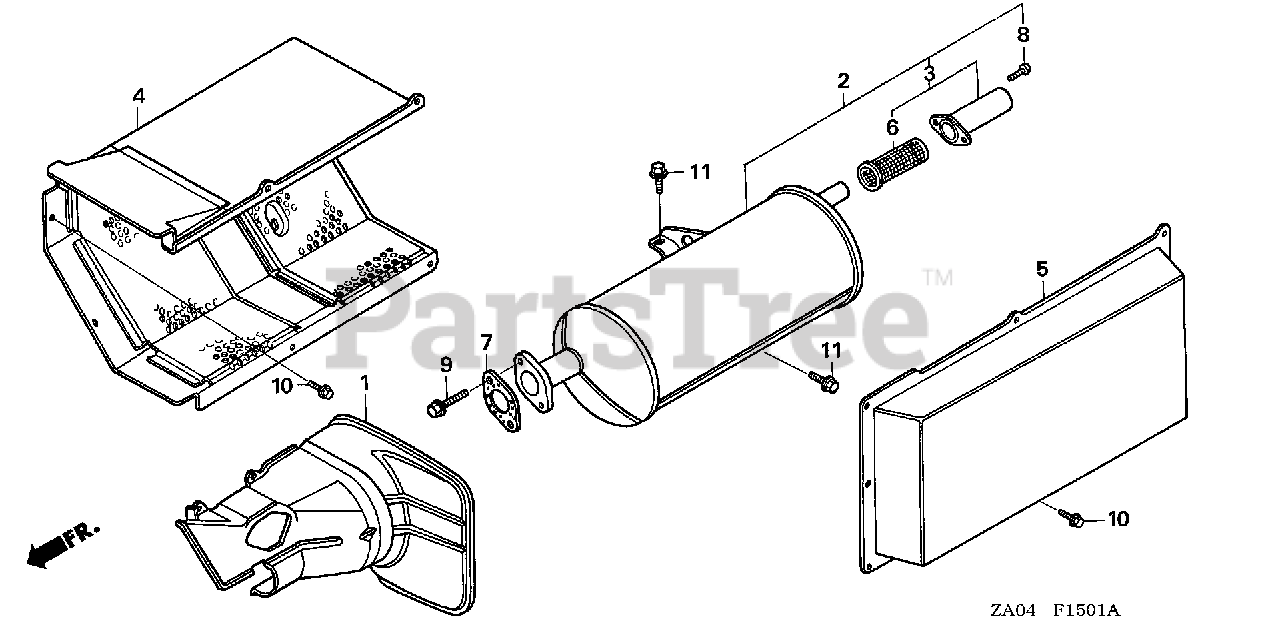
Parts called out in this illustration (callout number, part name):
1	COVER, EX.
3	CAP SET, ARRESTER (NOT AVAILABLE)
4	SEPARATOR A, MUFFLER
5	SEPARATOR B, MUFFLER
6	ARRESTER, SPARK
7	GASKET, MUFFLER
8	SCREW, PAN (5X8)
9	BOLT, FLANGE (8X20) Use up to Engine SN 1609606.
10	BOLT, FLANGE (6X10)
11	BOLT, FLANGE (8X20) Use up to Engine SN 1609606.
